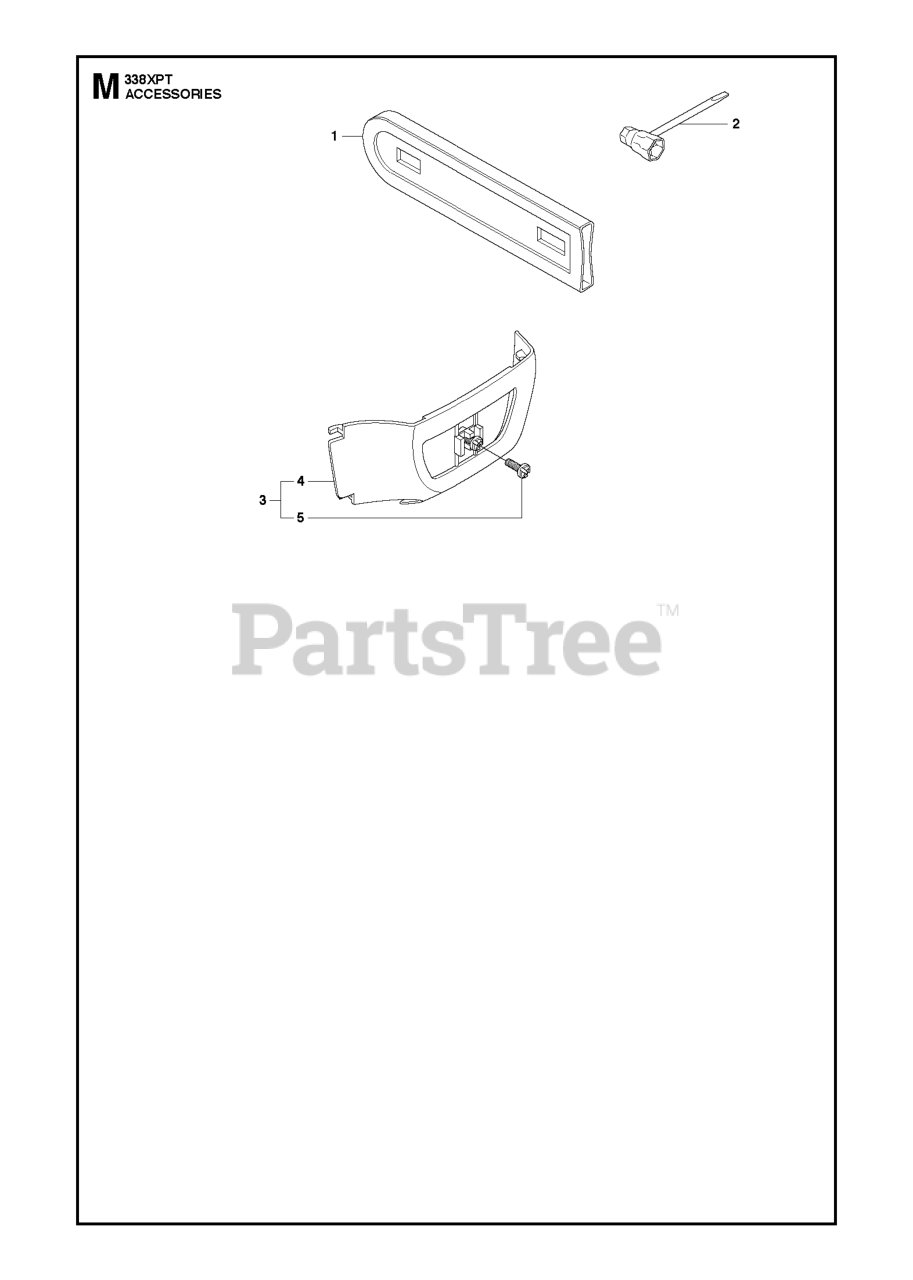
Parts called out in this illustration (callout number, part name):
1	BAR PROT/13-16""
2	COMBI TOOL
3	WINTER COVER ASSY
4	WINTER COVER
